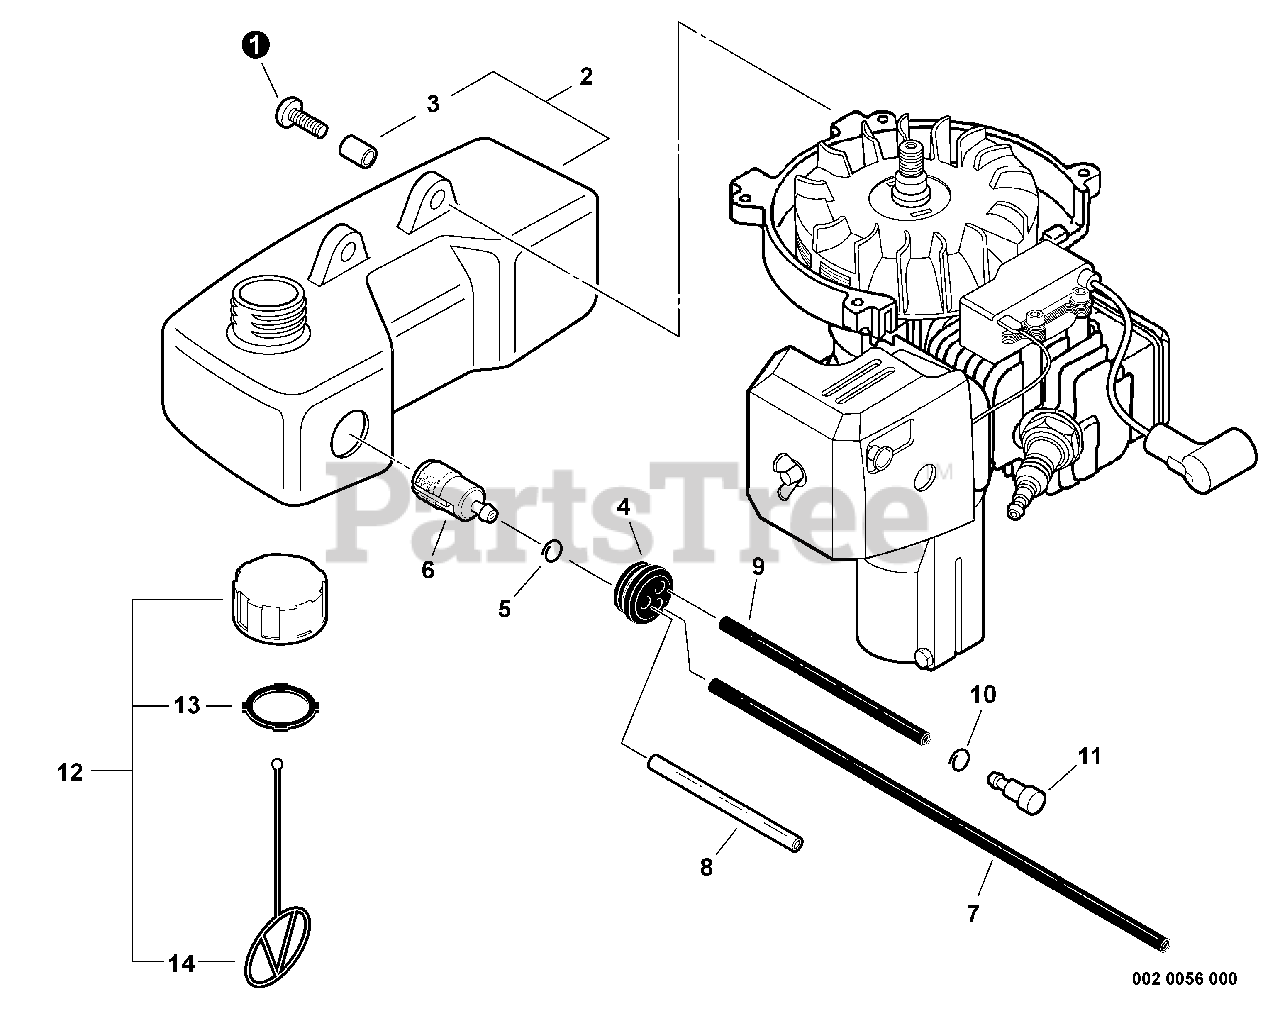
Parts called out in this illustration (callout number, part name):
1	SCREW - 5X15
2	TANK, FUEL
5	CLIP - 6
6	FILTER, FUEL
7	PIPE - 3X5X210 -- BLACK
8	PIPE - 3X6X50 -- CLEAR
9	PIPE - 3X5X70 -- BLACK
10	CLIP - 5.5
11	VENT, FUEL TANK
12	CAP ASSY - BLACK
13	GASKET, CAP
14	CONNECTOR, CAP
